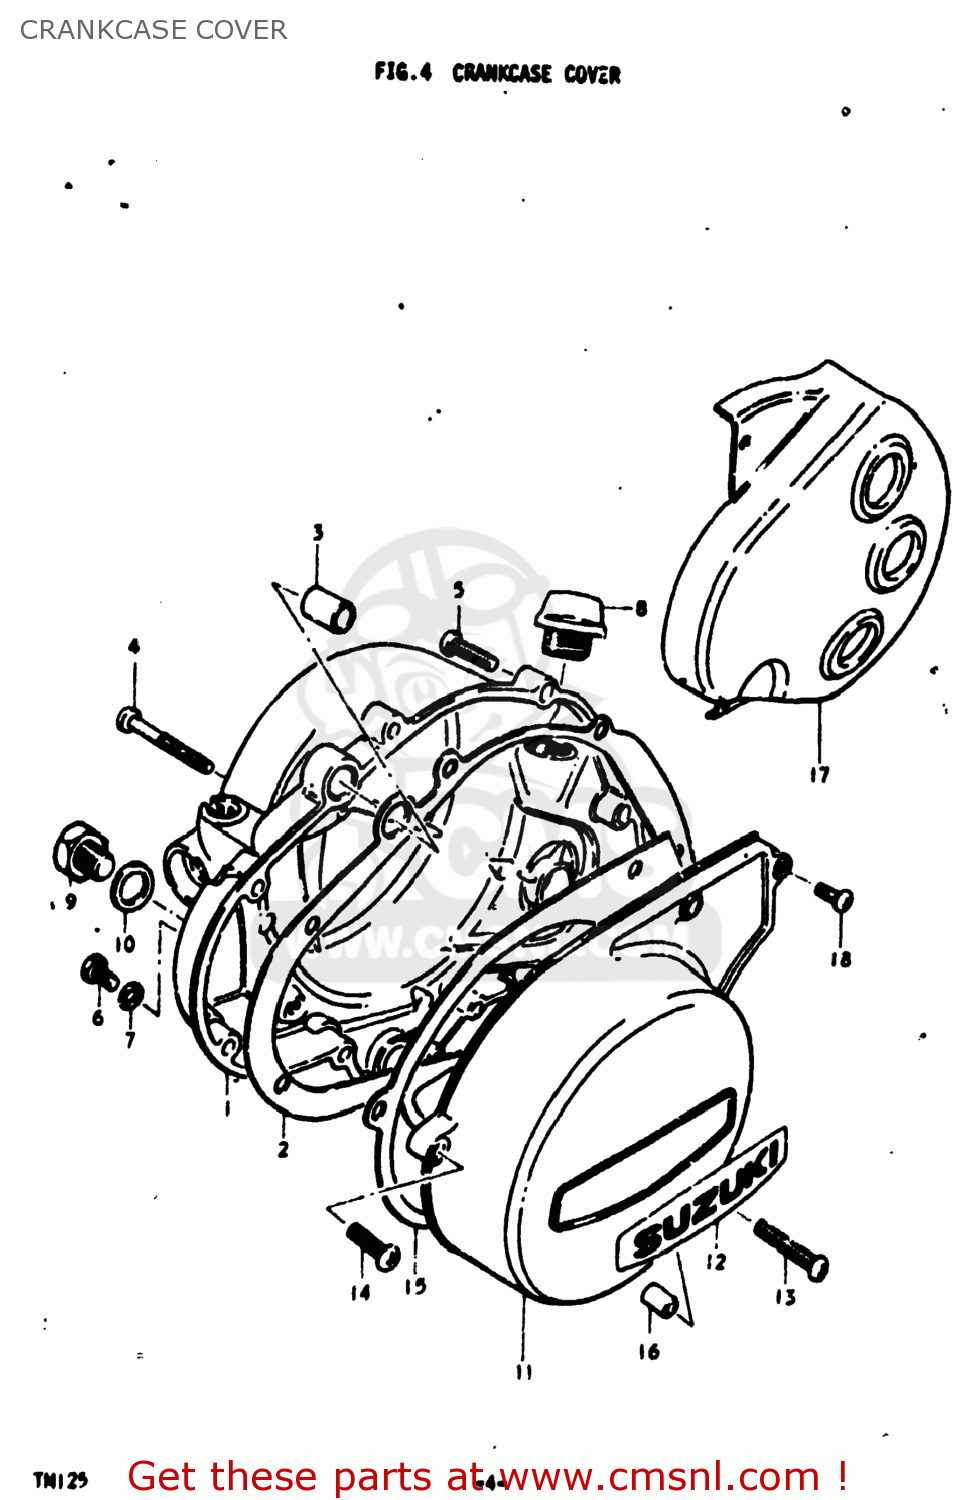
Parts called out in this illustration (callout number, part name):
1	COVER,CLUTCH
2	GASKET,CLUTCH COVER (MCA)
3	PIN
4	SCREW (6X45)
5	SCREW
6	SCREW(6X10)
7	GASKET(6.2X11X1) (NAS)
8	PLUG,OIL FILTER
9	PLUG
10	GASKET(14X19.2X2) (NAS)
11	COVER
12	EMBLEM
13	SCREW
14	SCREW
15	GASKET,CLUTCH COVER (NAS)
16	PIN
17	COVER,ENGINE SPROCKE MATT
18	SCREW
